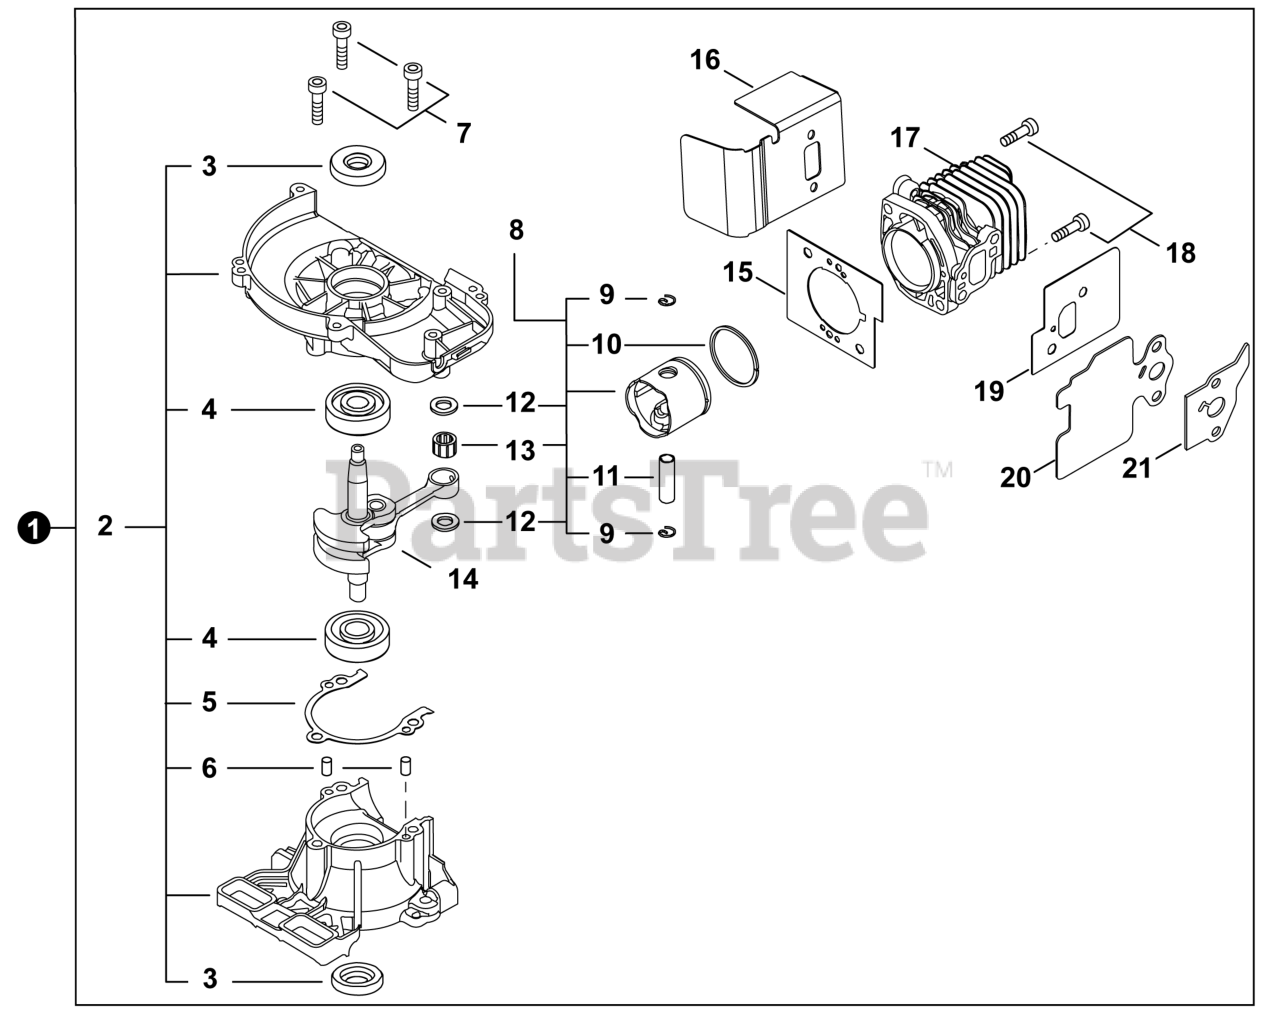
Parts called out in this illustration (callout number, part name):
1	SHORT BLOCK
2	CRANKCASE KIT
3	SEAL, OIL
4	BEARING, BALL
5	GASKET, CRANKCASE
6	PIN, LOCATING 4x8
7	BOLT 5x28
8	PISTON KIT
9	RING, SNAP
10	RING, PISTON
11	PIN, PISTON 8
12	WASHER, THRUST
13	BEARING, NEEDLE
14	CRANKSHAFT ASSY
15	GASKET, CYLINDER
16	HEAT SHIELD, EXHAUST
17	CYLINDER
19	GASKET, INTAKE
20	HEAT SHIELD, INTAKE
21	GASKET, INTAKE
